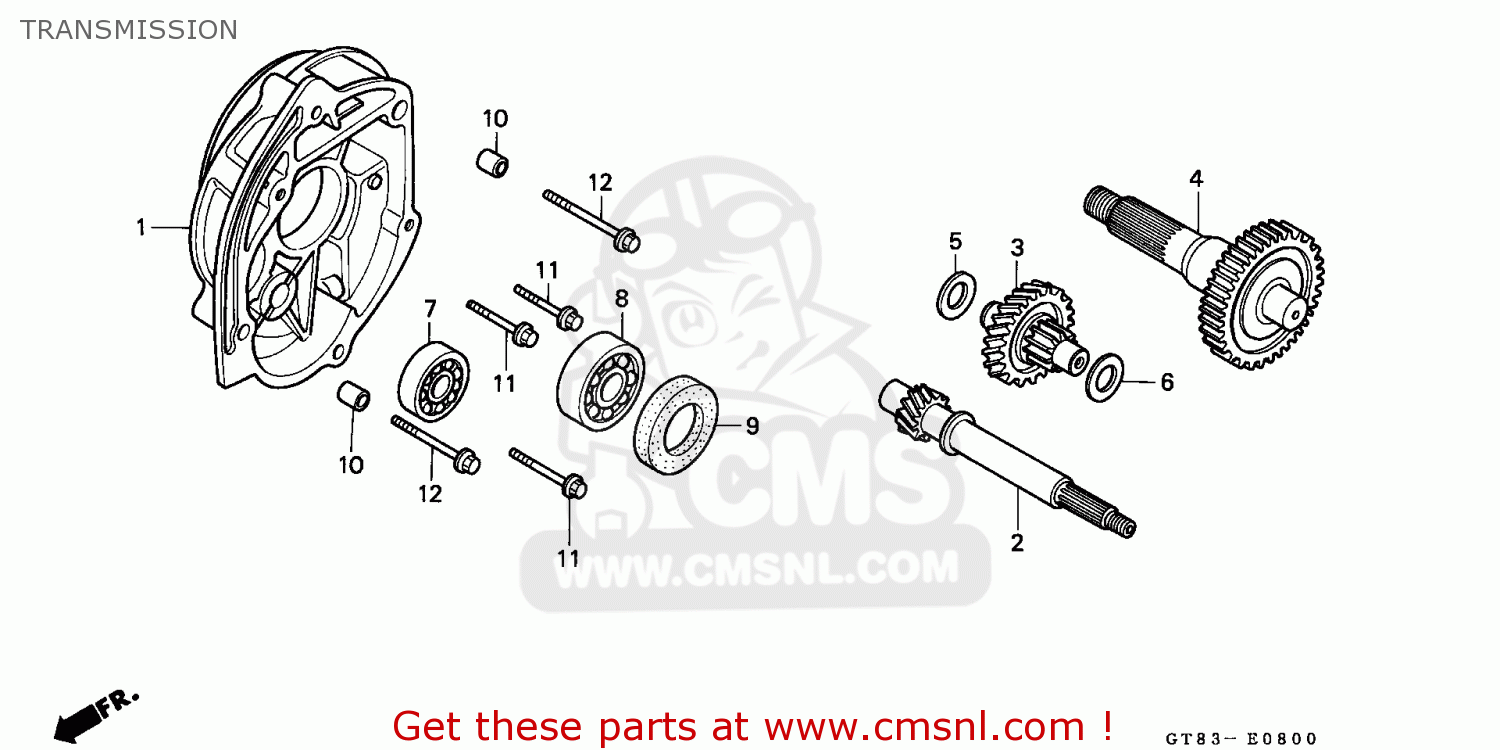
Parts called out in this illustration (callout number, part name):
1	CASE COMP,MISSION
2	DRIVE SHAFT
3	SHAFT COMP,COUNTE
4	GEAR COMP,FINAL
5	WASHER SIDE 14MM
6	WASHER,14MM
7	BEARING,RADIAL BA
8	BEARING,RADIAL BA
9	OIL SEAL,24X40X7
10	PIN,KNOCK 10X20
11	BOLT,FLNAGE,6X35
12	BOLT,FLANGE,6X45
